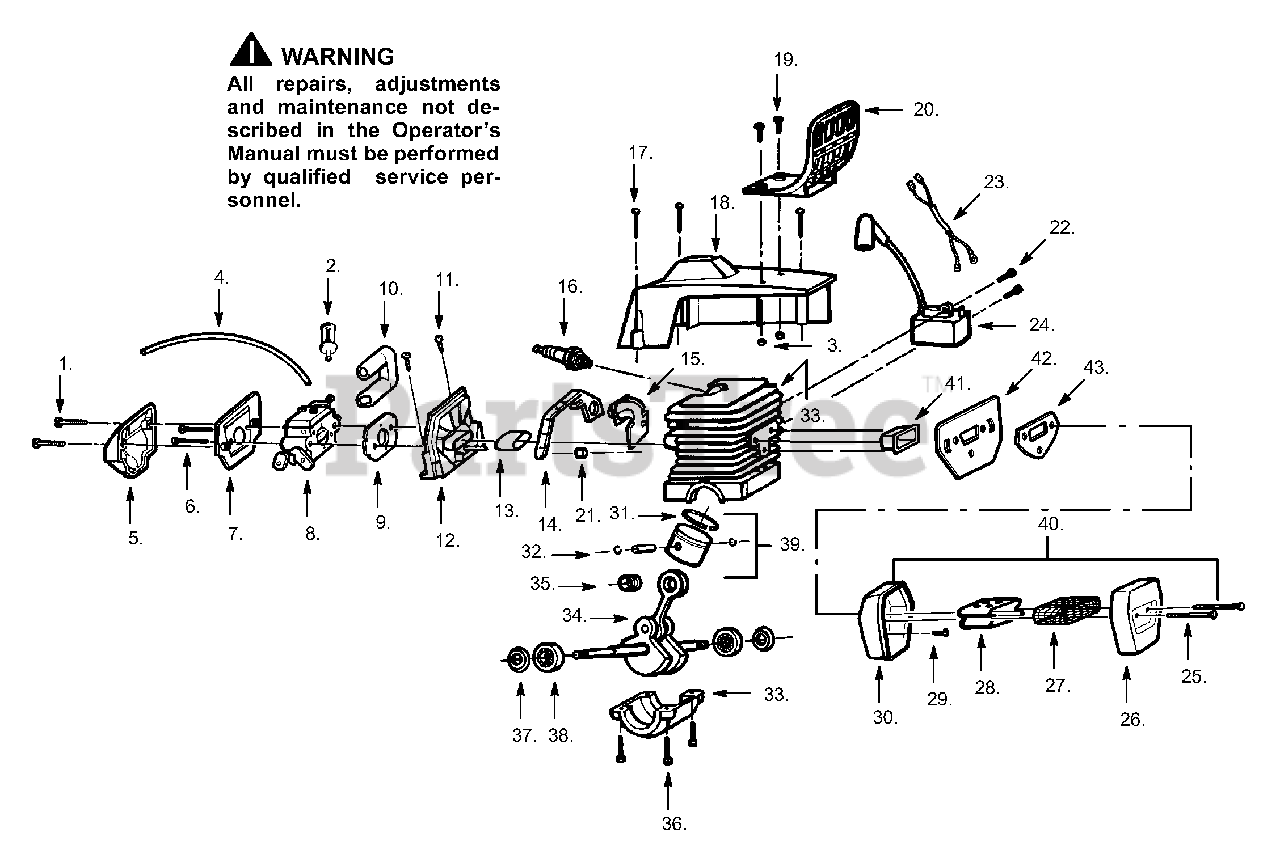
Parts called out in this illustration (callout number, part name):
2	Fuel Pick-up
4	Fuel Line
5	Air Filter (Top)
7	Air Filter (Bottom)
8	Carburetor Type 1,2,3 & 4
8	Carburetor Type Type 5
9	Carb. Gasket
10	Carb. Grommet Type 1,2,3 & 4
10	Carb. Grommet Type 5
11	Screw
12	Carb. Adaptor
13	Intake Sleeve
14	Turbo Clean Seal
15	Turbo Air Cleaner Ass'y.
16	Spark Plug (CJ-7Y)
17	Screw
18	Cylinder Shield
20	Handguard
21	Impulse Seal
23	Switch Wire Ass'y.
24	Ignition Module
25	Muffler Bolt 5mm
25	Muffler Bolt 6mm
26	Muffler Cover
27	Spark Screen
28	Diffuser
30	Muffler Body
31	Piston Ring 2500/2600
32	Piston Pin Retainer
33	Cylinder Kit 2200 40cc
33	Cylinder Kit 2200 36cc
34	C'shaft & Rod Ass'y.
35	Piston Pin Bearing
37	C'shaft Seal
38	C'shaft Bearing
39	Piston Kit
40	Muffler Kit
41	Heat Insulator
42	Muffler Plate
43	Muffler Gasket
